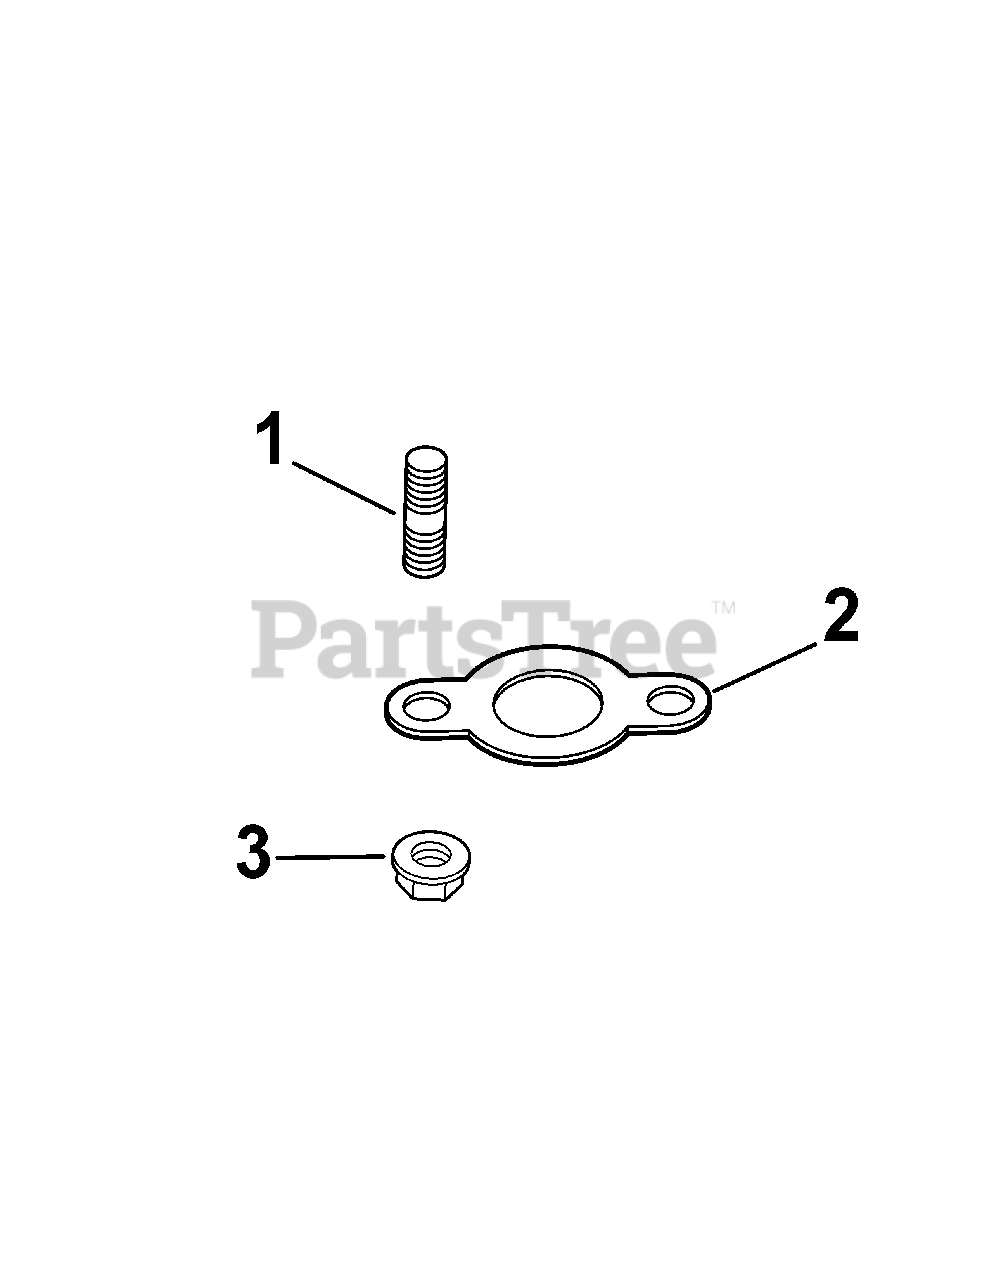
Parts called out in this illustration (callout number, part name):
1	Stud M8x1.25x33 (4)
2	Gasket , exhaust manifold (2)
3	Nut, hex. Flnage M8 x 1.25 (5)
